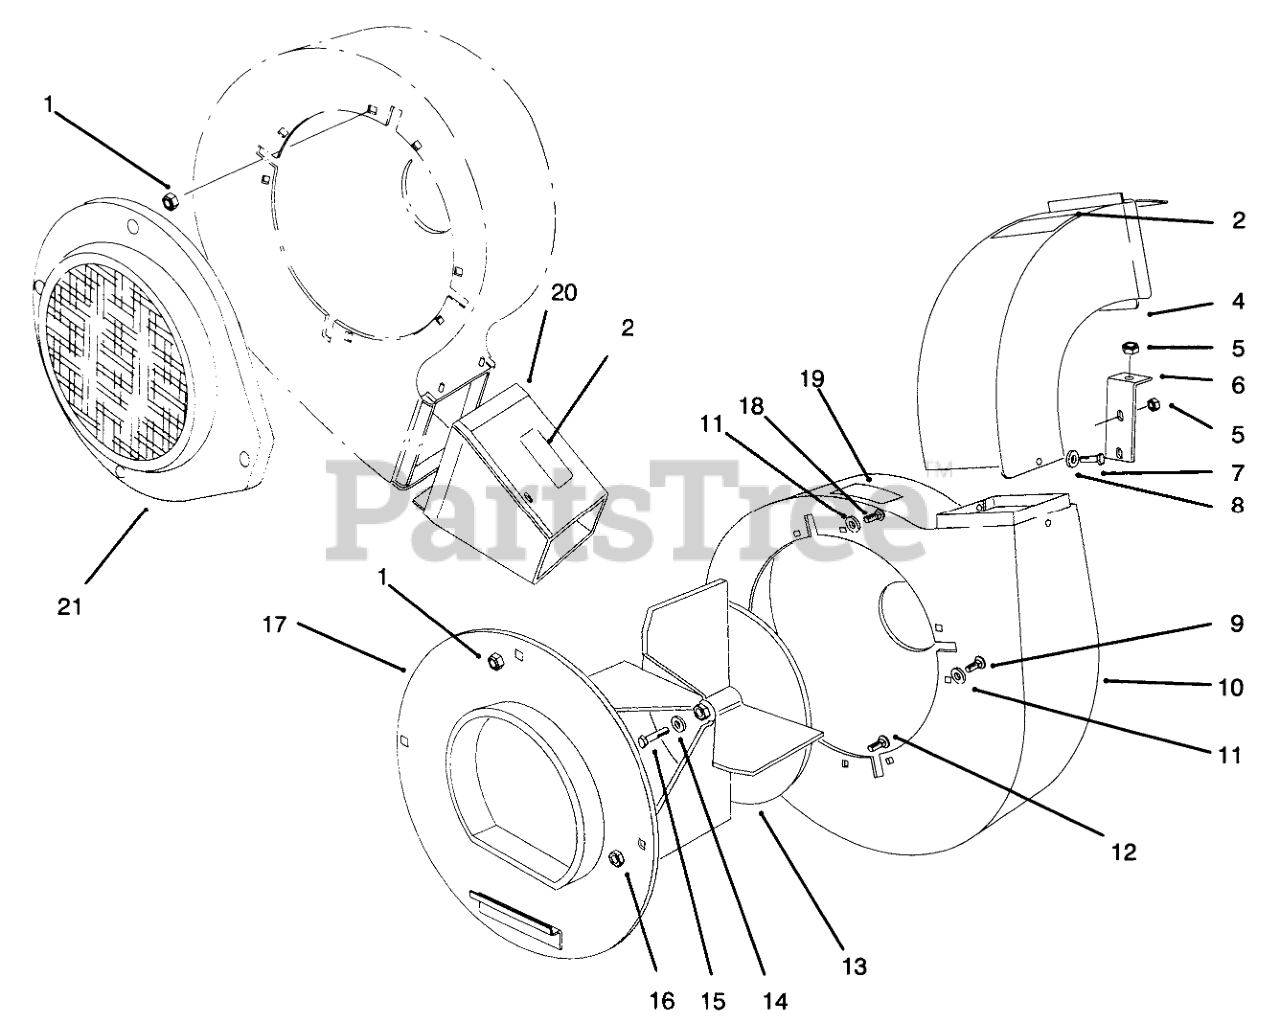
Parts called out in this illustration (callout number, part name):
1	NUT-FLANGE
2	DECAL-CAUTION, BAG
4	Chute-Vacuum
5	NUT-LOCK, NI
6	Bracket-Housing
7	SCREW-HH
8	WASHER-BELLEVILLE
9	SCREW-CARR
10	Blower Housing
11	WASHER-FLAT
12	SCREW-CARR
13	Fan Assembly
14	WASHER-BELLEVILLE
15	SCREW-HH
16	NUT-LOCK, NI
17	Blower Cover
18	BOLT-CARR
19	Decal-Warning
20	Blower-Exhaust
21	INTAKE-BLOWER
